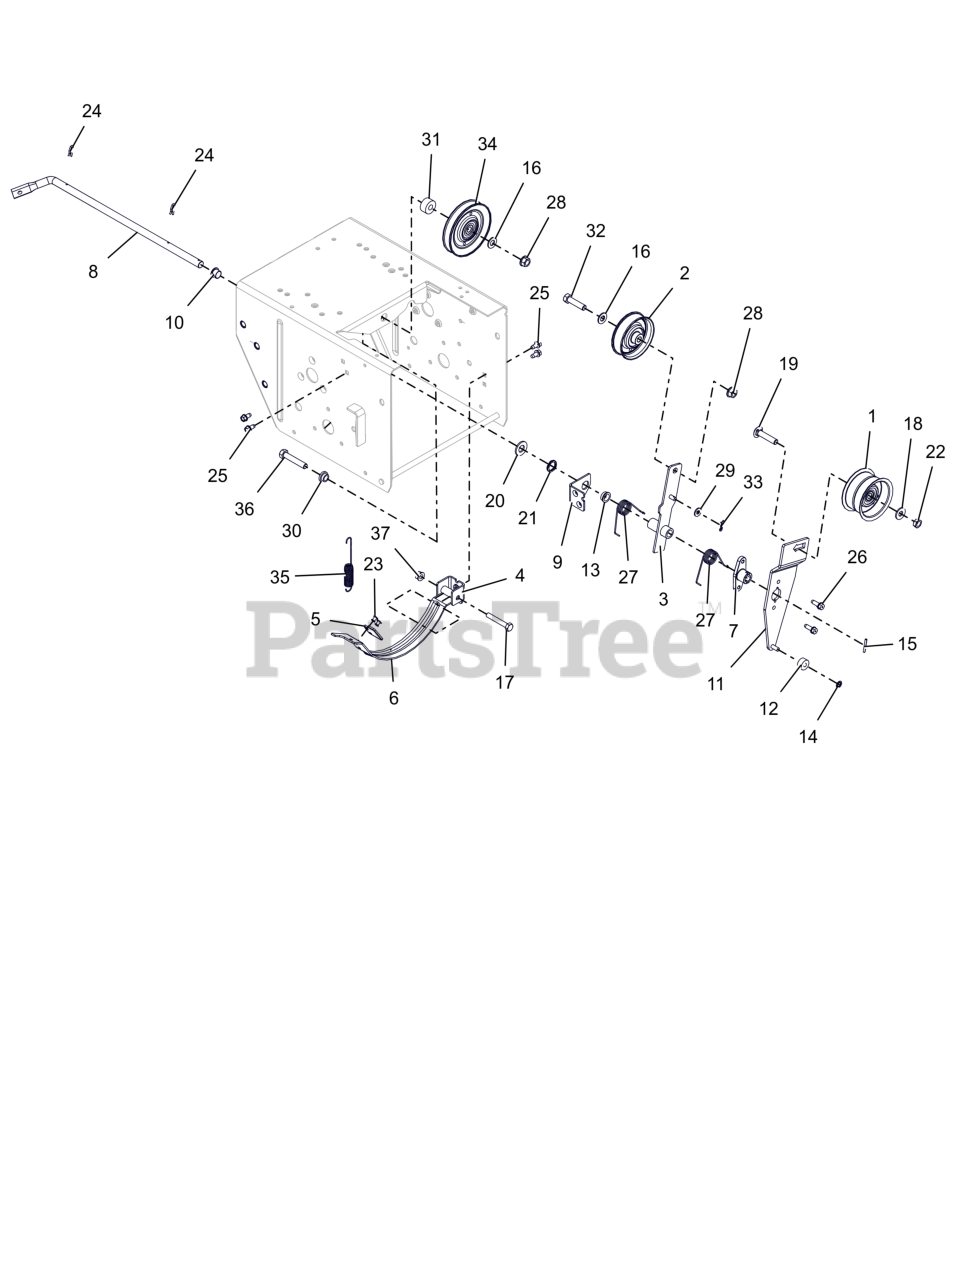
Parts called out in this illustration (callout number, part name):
1	IDLER, FLANGE -2.75 OD X .375 ID
2	IDLER, FLAT - 3.05" X .75"
3	ARM, TRACTION CLUTCH
4	PIVOT, BRAKE
5	PAD, BRAKE
6	ARM, BRAKE-ATTACHMENT
7	HUB, BRAKE ARM
8	ARM, ATTACHMENT
9	BRACKET, SUPPORT
10	BUSHING, POLYLINER-.50 SPLIT
11	ARM, IDLER - ATTACHMENT
12	BSHG,SLV .265 X .625 X .375
13	BSHG,FLANGE .500X.625X.270X.75
14	RG-RTNG-EXT .250X.010
15	PIN-ROLL .125X1.00
16	WSHR,FLT .406X.812X.065 ZCC
17	BLT, HEX .31-18X2.00 G5 ZCC
18	WSHR,FLT .375X.875X.083 ZCC
19	BLT, RHSSN .38-16X1.75 G5 ZCC
20	WSHR,FLT .531X1.062X.095 ZCC
21	WAVE SPRING .600X.875X.25FH
22	NUT-LK-CTR-JAM .375-16 GB ZCC
23	RVT, POP .1875 ZCC
24	CLIP, SPRING
25	SCR-TAP .25-20X.50 HWH ZCC
26	SCR,TAP .25-20X.75 HWH TR ZCC
27	SG-TORS .067X.88
28	NUT-LK-TOP-FLG .38-16 ZC120
29	WSHR,FLT .281X.625X.065 ZCC
30	BSHG, FLANGE .391X.56X.313X.75
31	BSHG,POCKET .391X.570X1.0X.450
32	BLT, HEX .38-16X1.50 G5 ZCC
33	PIN, HAIR #178 .06X.77 ZCC
34	SHV, .38"ID X 4.00"OD V-IDLER
35	SG-TENS .056X.60X4.40
36	BLT,HEX .38-16X2.00 G5 ZCC
37	NUT-LK-TOP-FLG .312-18 GF ZCC
